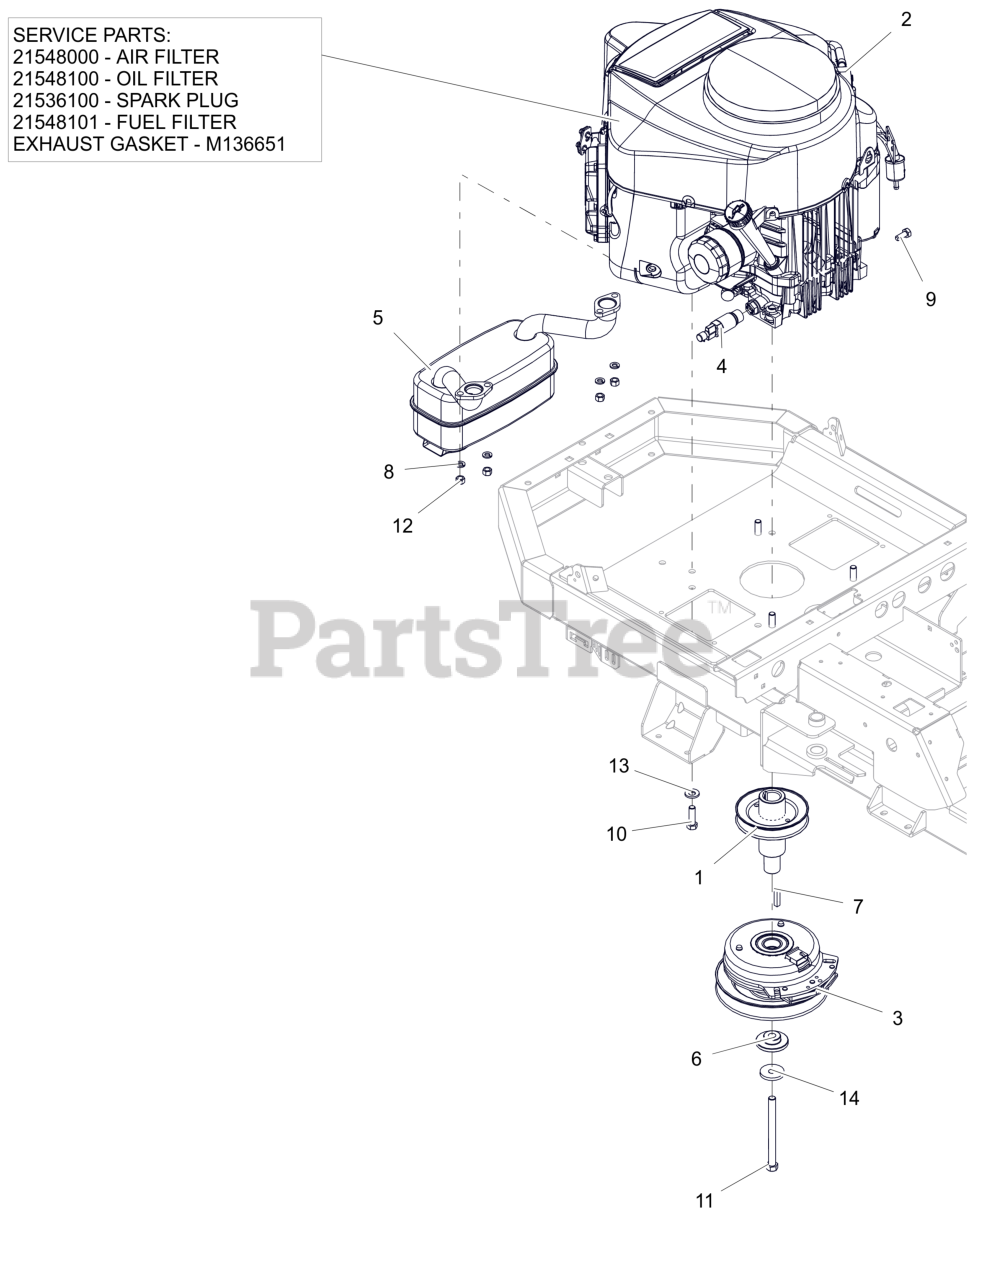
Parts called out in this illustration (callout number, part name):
1	WLDMT, DRIVE SHEAVE (LONG)
2	ENGINE, KAWASAKI
2	AIR FILTER, KAWASAKI FR
2	OIL FILTER, KAWASAKI FR
2	PLUG, SPARK
2	FUEL FILTER-KAWASAKI FR
2	GASKET, MUFFLER #
3	CLUTCH,105FTLB MONOPOLE 6.83"
4	DRAIN, OIL M20X2.5
5	MUFFLER - KAWASAKI
6	BSHG-FLG .469X1.06X.574X2.0
7	KEY-SQ .25 X 1.25 X .25 SAE
8	WSHR,LK-REG .312X.078 ZCC
9	BLT, HEX M8-1.25X20 G8.8 ZCC
10	BLT, HEX .38-16X1.25 G5 ZCC NT
11	BLT, HEX .44-20X5.00 G8 ZCC NT
12	NUT, HEX M8-1.25 GR8.8 ZC120
13	WASHER, 3/8" SPRING DISC
14	WASHER, 7/16" SPRING DISK
